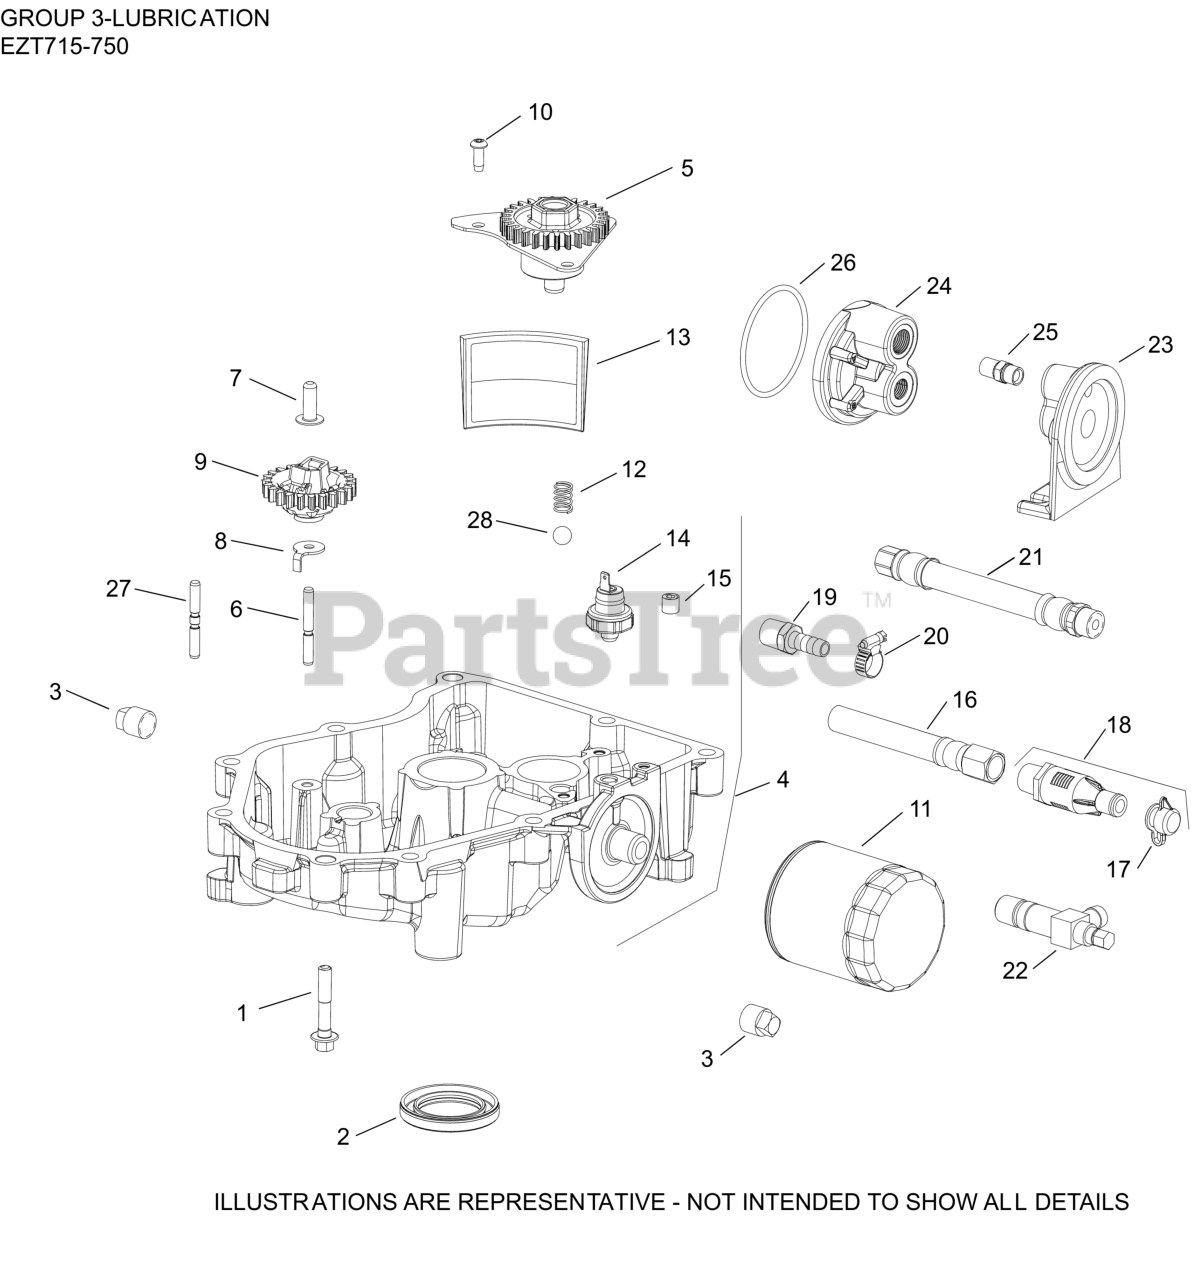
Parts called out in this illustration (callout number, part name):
1	SCREW, FLG M8X1.25X45
3	PLUG, SQ HD PIPE 3/8"
5	PUMP ASSEMBLY, OIL
7	PIN, GOVERNOR REGULATING
8	TAB, LOCKING
9	KIT, GOVERNOR GEAR
11	OIL FILTER
12	SPRING, COMPRESSION
13	SCREEN, OIL
14	SENSOR, OIL PSI
27	SHAFT, GOVERNOR GEAR
28	PRESSURE RELIEF BALL
NI	SCREW, BUTTON HEAD
